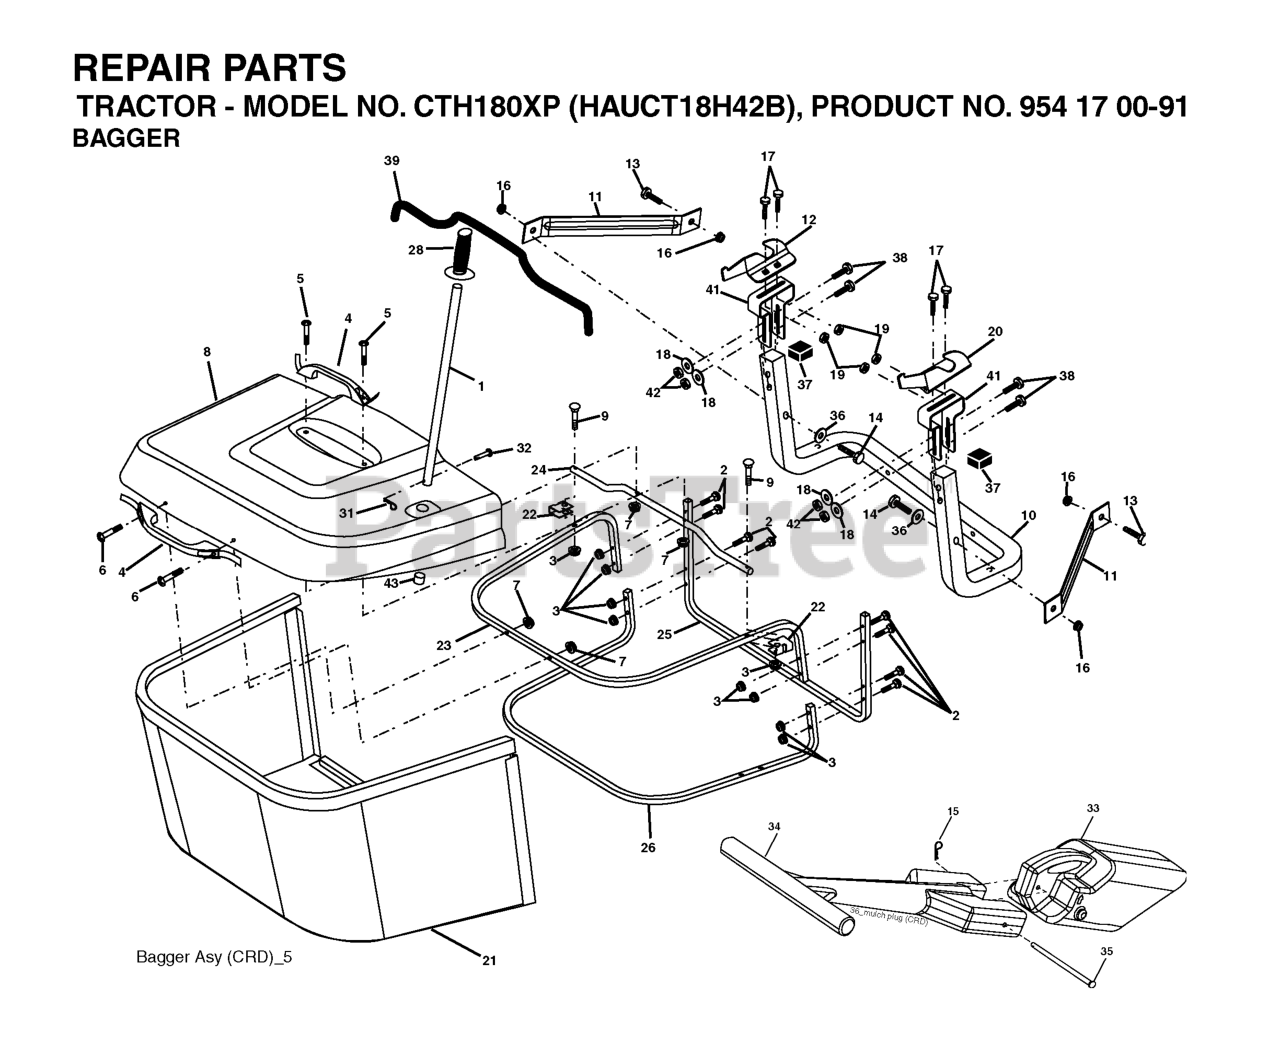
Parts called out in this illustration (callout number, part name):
1	TUBE HANDLE
2	Bolt Carriage 1/4-20 x 2.0 Gr.5
3	NUT T
4	HANDLE.BAGGER.W/LVRS.BLK.CRD
5	SCREW.PAN.HEAD
6	REPL BY 532 75 00-29
8	COVER.PNT.BGR.CRD.WSLOTS.MS668
9	Bolt Carriage 1/4-20 x 2.25d x Gr.5
10	TUBE
11	BRACKET.SUPPORT.UPPER.BAG.CRD
14	BOLT-HEX EAK
15	RETAINER CLIP
16	NUT LOCK FLG 3/8-16 UNC
17	RP BOLT 5/16-18 X3/4 ZN/YEL GR
18	WASHER M
19	NUT LOCK HEX FLANGE 5/16-18
20	BRACKET
21	GRASS BAG
22	BRKT.SIDE.BAG.CRD
23	TUBE.UPPER.BAG.CRD
24	TUBE.PIVOT.BAG.CRD.BLACK
26	TUBE.LOWER.BAG.CRD
28	GRIP.HANDLE.BLACK
31	RETAINER M
32	RIVET,DRILLED
33	MULCH PLUG, CTH150
34	HANDLE.MULCHER.92.CRD (2 2)
36	WASHER
37	Plug Support Bagger CRD
38	BOLT.5/16-18X2.5
39	SEAL.TRIM.37'
41	BRKT.VERT.ADJ.BAGGER.CRD
42	NUT.71038.31-18.HEX.NYLOCK
43	PLUG, TUBING END
